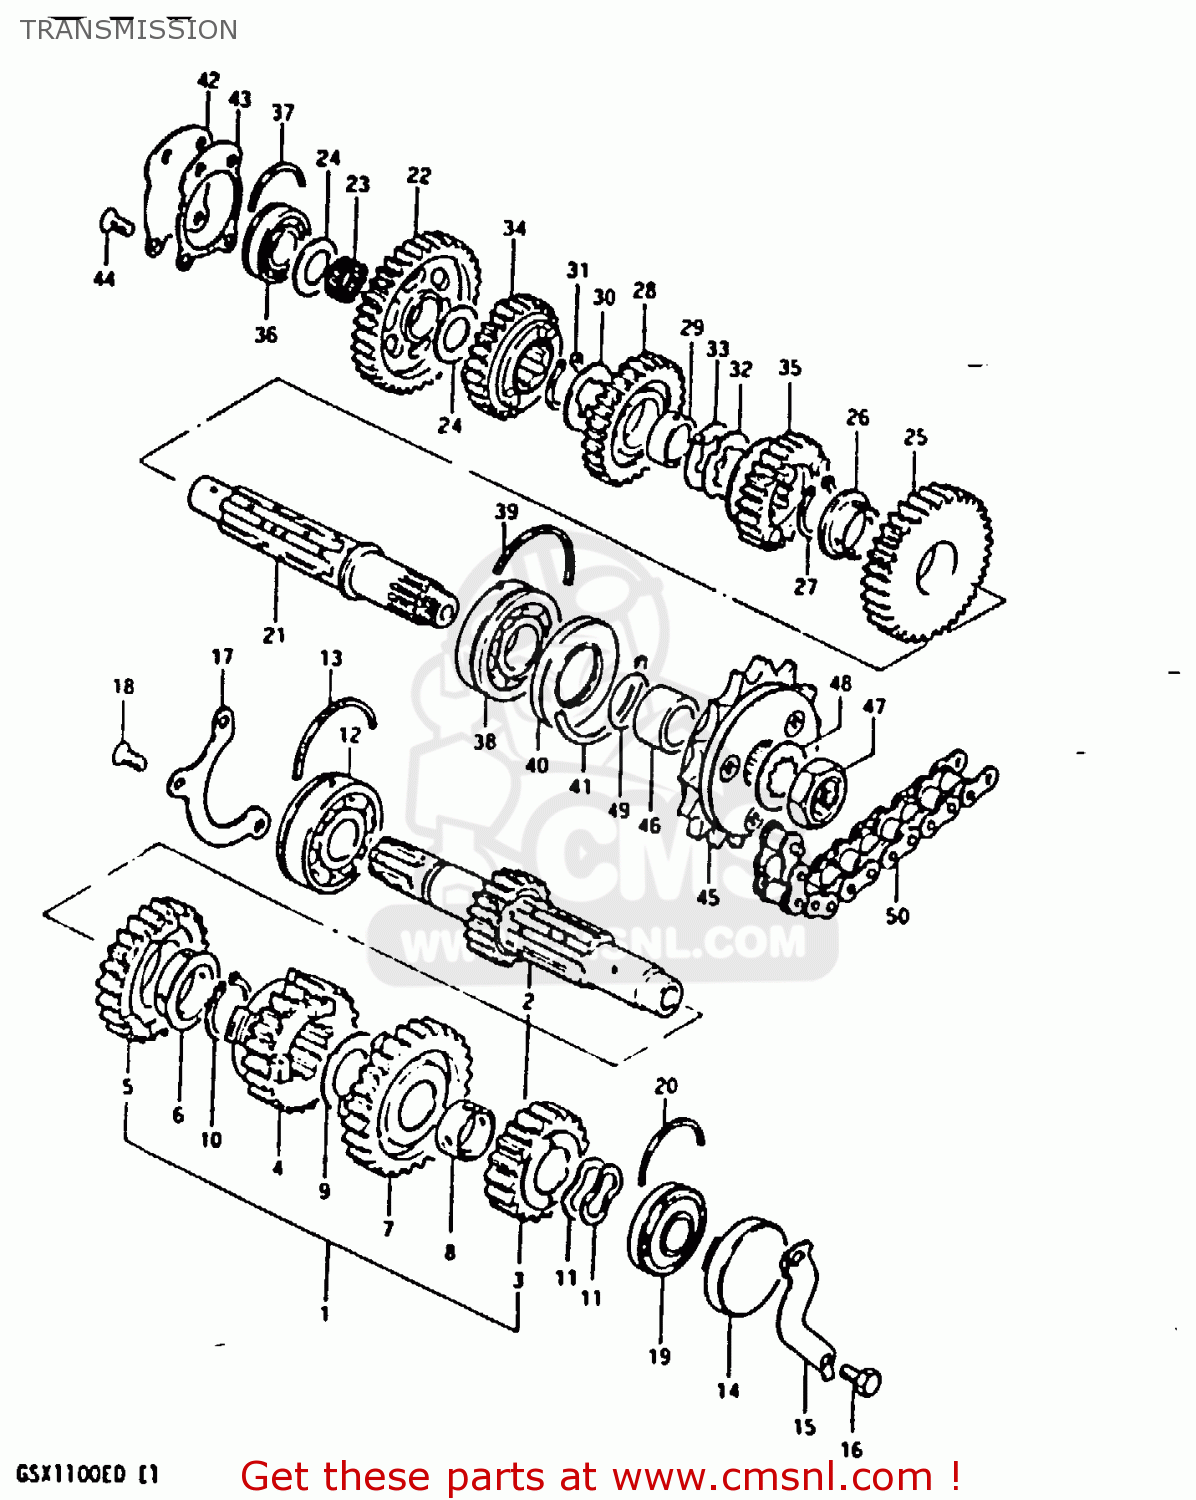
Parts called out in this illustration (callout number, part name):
1	SHAFT,COUNTER
2	SHAFT,COUNTER
3	GEAR,SECOND DRIVE
4	GEAR,3RD DRIVE(NT:21)
5	GEAR,FOURTH DRIVE
6	BUSH(28X32X2)
7	GEAR,FIFTH DRIVE
8	BUSHING
9	WASHER
10	CIRCLIP
11	WASHER
12	BEARING(25X62X17)
13	C-RING
14	PLUG
15	RETAINER,CL PUSH ROD OIL SEAL
16	BOLT
17	RETAINER,CNTR SHAFT BEARING
18	SCREW
19	BEARING(20X47X14)
20	C RING
21	SHAFT,DRIVE
22	GEAR,FIRST DRIVEN (NT:35)
23	BEARING(20X24X10).8
24	WASHER
25	GEAR,SECOND DRIVEN
26	BUSH(28X32X2)
27	CIRCLIP
28	GEAR,THIRD DRIVEN
29	BUSH,3RD DRIVEN GEAR
30	WASHER,LOCK
31	CIRCLIP
32	WASHER,LOCK
33	WASHER
34	GEAR,FOURTH DRIVEN
35	GEAR,FIFTH DRIVEN
36	BEARING
37	C RING
38	BEARING(25X62X17)
39	C-RING
40	SEAL,OIL(32X62X7)
41	C RING
42	PLATE,DRIVE SHAFT
43	GASKET,DRIVESHAFT PLATE (MCA)
44	SCREW
45	SPROCKET,ENGINE
46	SPACER(25X32X18.6)
47	NUT
48	WASHER
49	O RING(D:1,ID:24.5)
50	CHAIN ASSEMBLY,DRIVE
